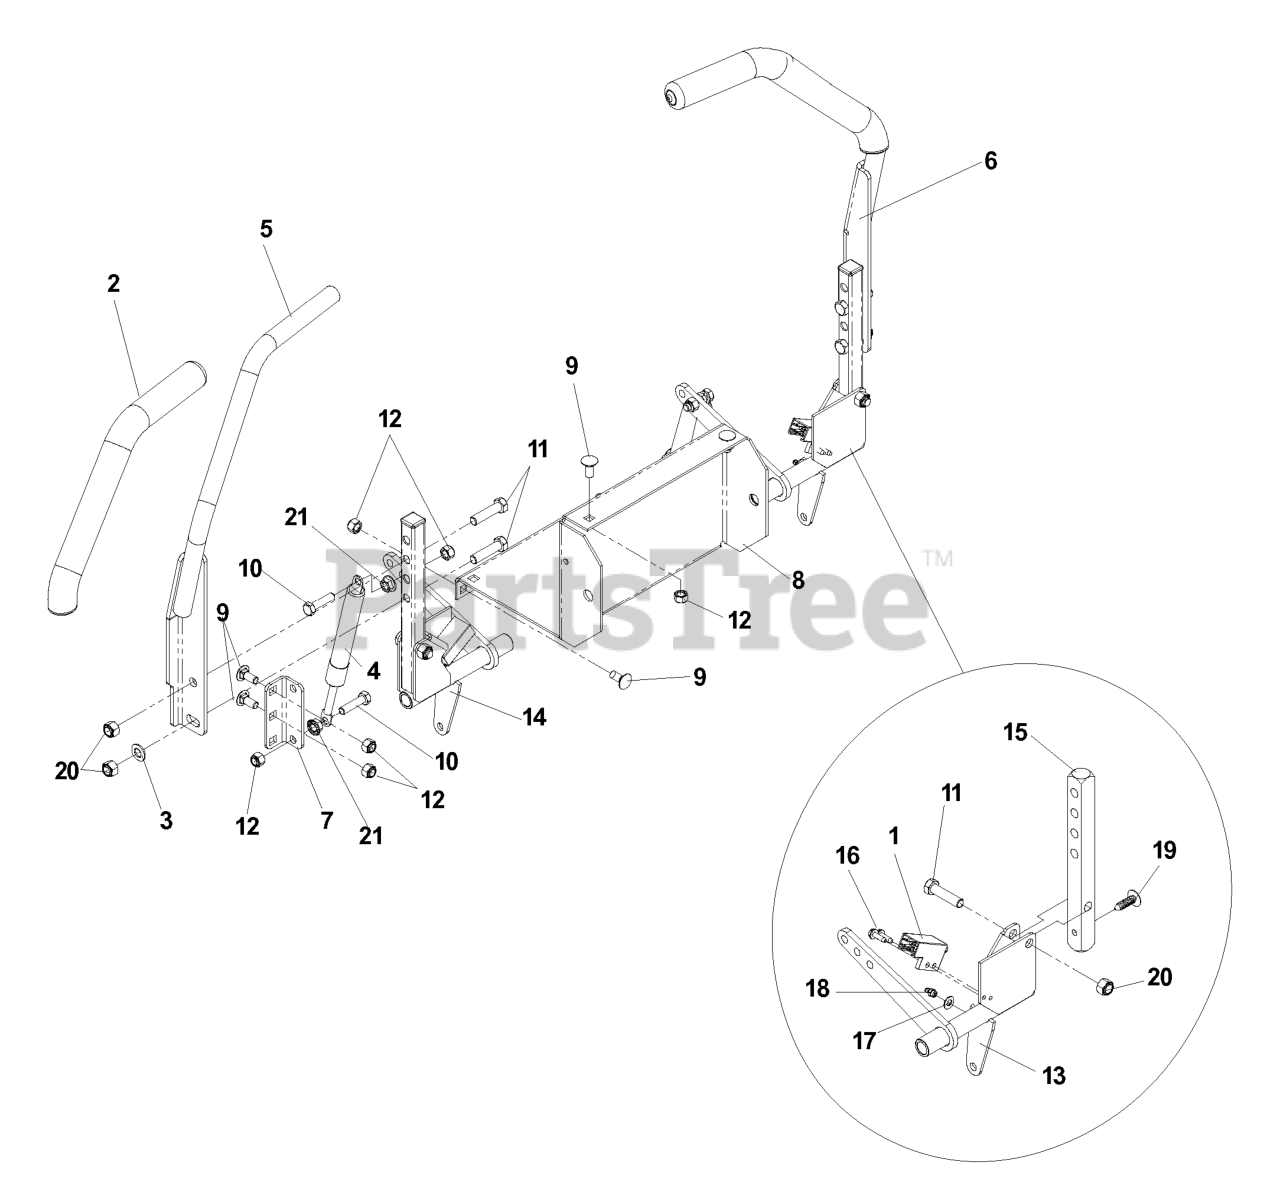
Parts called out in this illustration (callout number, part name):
1	SWITCH, INTERLOCK
3	WASHER, 3/8 DISC SPRING SPEC
5	RT DRIVE LEVER WLDMT
6	LT DRIVE LEVER WLDMT
7	DAMPENER BRACKET
8	BATTERY TRAY
9	BOLT 5/16C X 3/4" CARRIAGE
10	HCS 5/16C X 1 1/4
11	HCS 3/8C X 1 1/2
12	NUT 5/16 NYLOC
13	CONTROL WELDMENT, LEFT
15	CONTROL ARM
16	SCREW #10 X 1/2 SELF TAPPING
18	ZERK
19	RIVET, NYLON PUSH-IN
20	NUT 3/8-16 NYLOC
21	NUT 5/16C WHIZ
